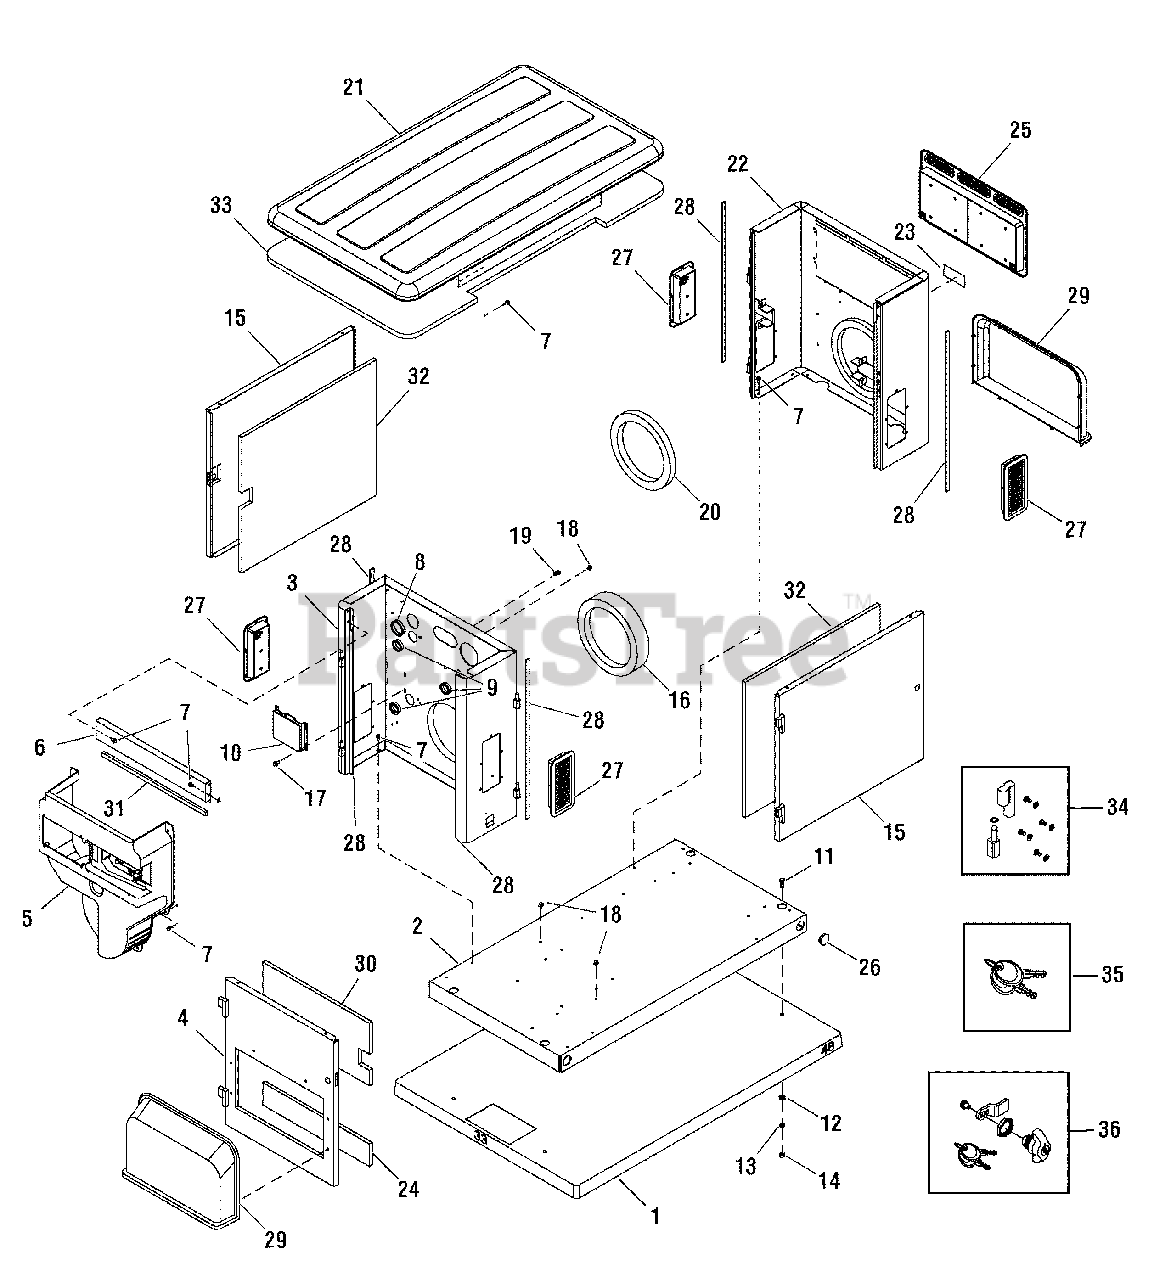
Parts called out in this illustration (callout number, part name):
1	PAD, Mounting w/Holes
3	ASSY, Bulkhead, Eng End
4	ASSY, Door, Eng. End
5	ASSY, Duct, Engine Air
6	ASSY, Support, Rail
7	SCREW, Hex Head, Trilobular, 1/4-20 x 1/2
8	BUSHING, Snap, 2"
9	BUSHING, Snap, 1-1/2"
10	REGULATOR, Voltage
11	* CAPSCREW, Hex Head, 3/8-16 x 1
12	* WASHER, Flat, 3/8 - M10
13	* WASHER, Lock 3/8
14	* NUT, 3/8-16
16	SEAL, Foam, Engine Air
17	HHS, Trilobular, #8-32 x 1/2
18	MOUNT, Tie Wrap
20	SEAL, Foam, Alt Inlet
21	ASSY, Roof/Siderails
22	ASSY, Bulkhead, Alt End
23	DECAL, Caution Hot Muffler
24	INSULATION, Engine Door, Bottom
25	ASSY, Vent, Exhaust
27	ASSY., Vent, Alt.
29	COVER, Air Intake Engine
30	INSULATION, Engine Door, Top
32	INSULATION, Front/Rear Door
33	INSULATION, Roof
34	KIT, Door, Hinge
36	KIT, Door Latch
